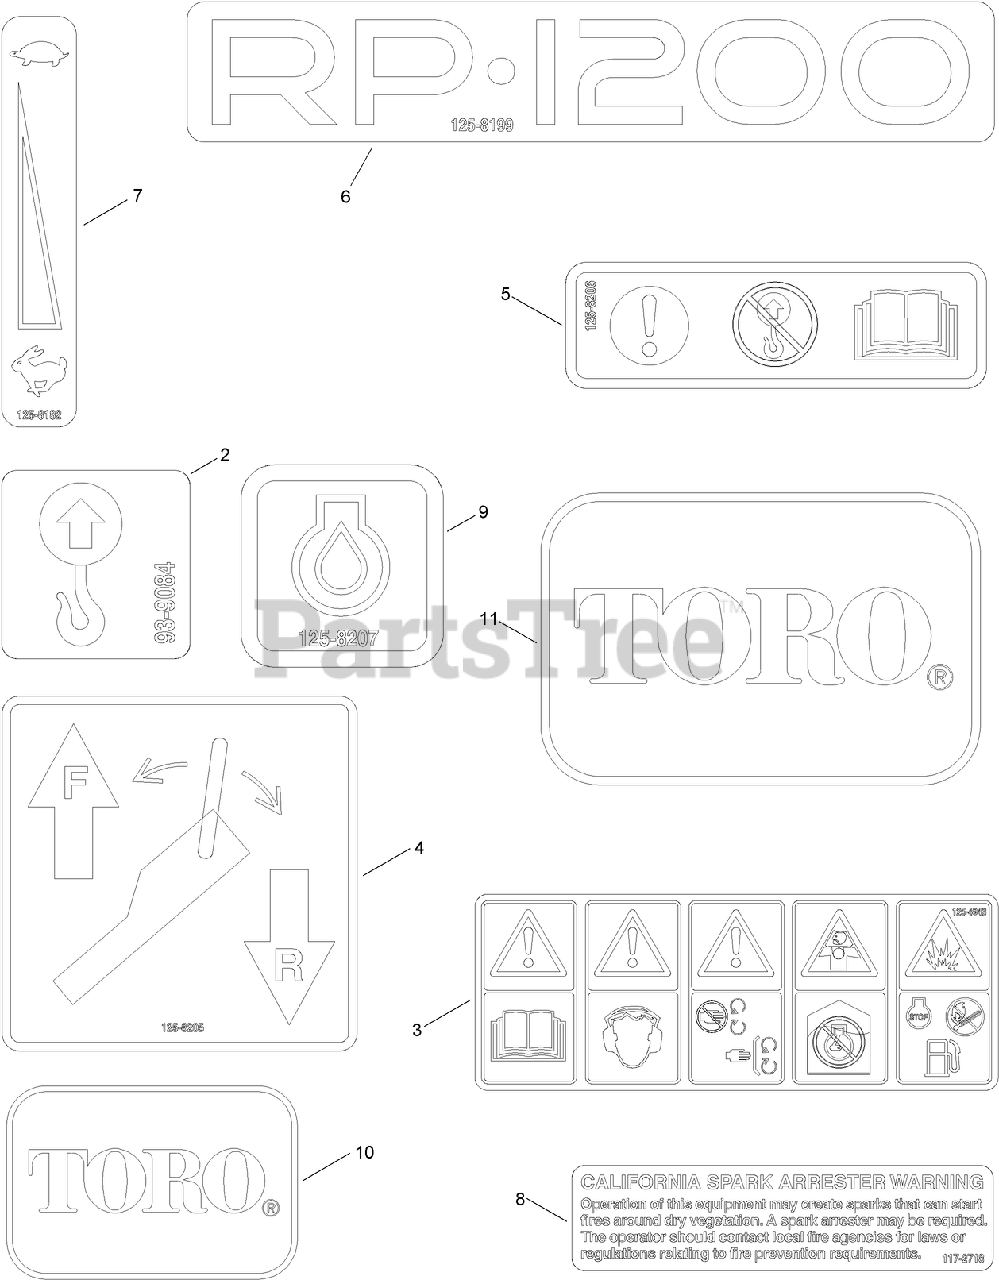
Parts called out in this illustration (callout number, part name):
2	DECAL-POINT, LIFT
3	DECAL-WARNING, PLATE
4	DECAL-OPERATION
5	DECAL-CAUTION
6	DECAL-RP-1200
7	DECAL-THROTTLE
8	DECAL-ARRESTER, SPARK
9	DECAL-OIL, ENGINE
10	DECAL
